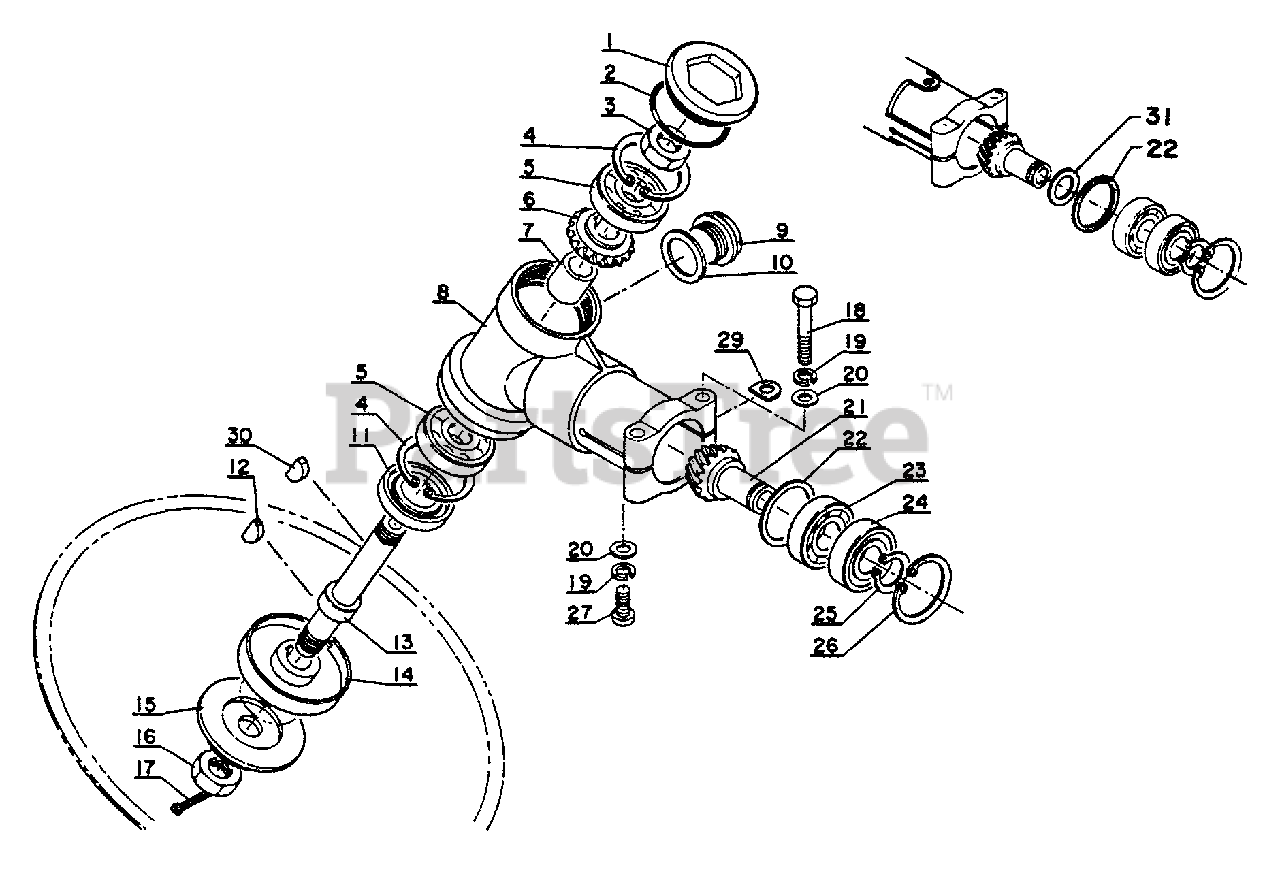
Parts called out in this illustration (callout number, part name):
1	COVER, GEAR CASE
2	O-RING
3	NUT 3N-10
4	E-RING 30
5	BEARING, BALL 6200
6	GEAR SET
7	SPACER
8	CASE, GEAR
9	FITTING, GREASE
10	GASING, GEAR
11	SEAL, OIL
13	DRIVESHAFT
14	PLATE, ADAPTER - UPPER
15	PLATE, ADAPTER - LOWER
16	NUT - 10 -- LEFT HAND
17	PIN, COTTER 2×22
18	BOLT 5×30
19	WASHER, SPRING 5
20	WASHER, FLAT 5.5×10×0.8
21	GEAR SET
23	BEARING, BALL 6001
24	BEARING, BALL 6001
25	RING, RETAINING - 12
26	RING, SNAP 28
27	SCREW 5×10
